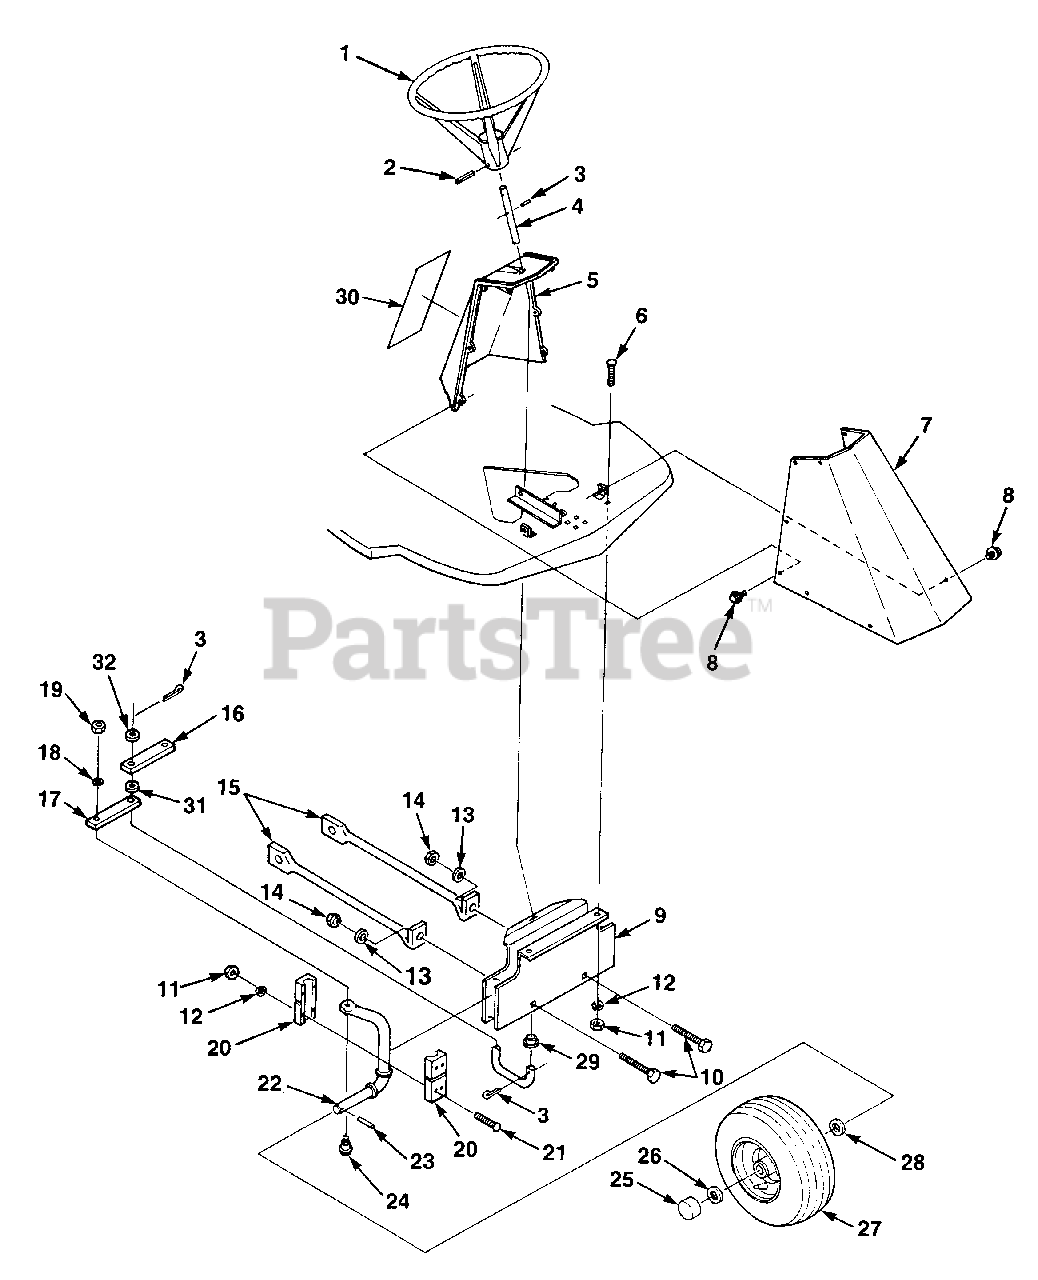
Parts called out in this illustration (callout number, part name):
1	STEERING WHEEL
2	PIN- Roll
3	PIN- Cotter
4	SHAFT- Steering
5	PANEL- Console
6	BOLT- Rd. Hd. Sq. 1/4-20 x .625
7	SUPPORT- Steer
8	SCREW- Hex washer
9	FRONT AXLE
10	SCREW- Hex head 3/8-16 x.750
11	NUT- Hex centerlock 1/4-20
12	WASHER- Plain 1/4"
13	WASHER- Plain 3/8"
14	NUT- Hex head centerlock 3/8-16
15	SUPPORT-Axle
16	LINK- Steer (R.H.)
17	LINK- Steer (L.H.)
18	WASHER- Flat
19	NUT- Hex centerlock
20	BEARING- Spindle
21	BOLT- Rd. Hd. sq. 1/4-20 x 1.750
22	SPINDLE- Wheel
23	PIN- Roll 5/32 x 1.25
24	BOLT- Shoulder
27	TIRE & HUB
30	DECAL- Instruction
